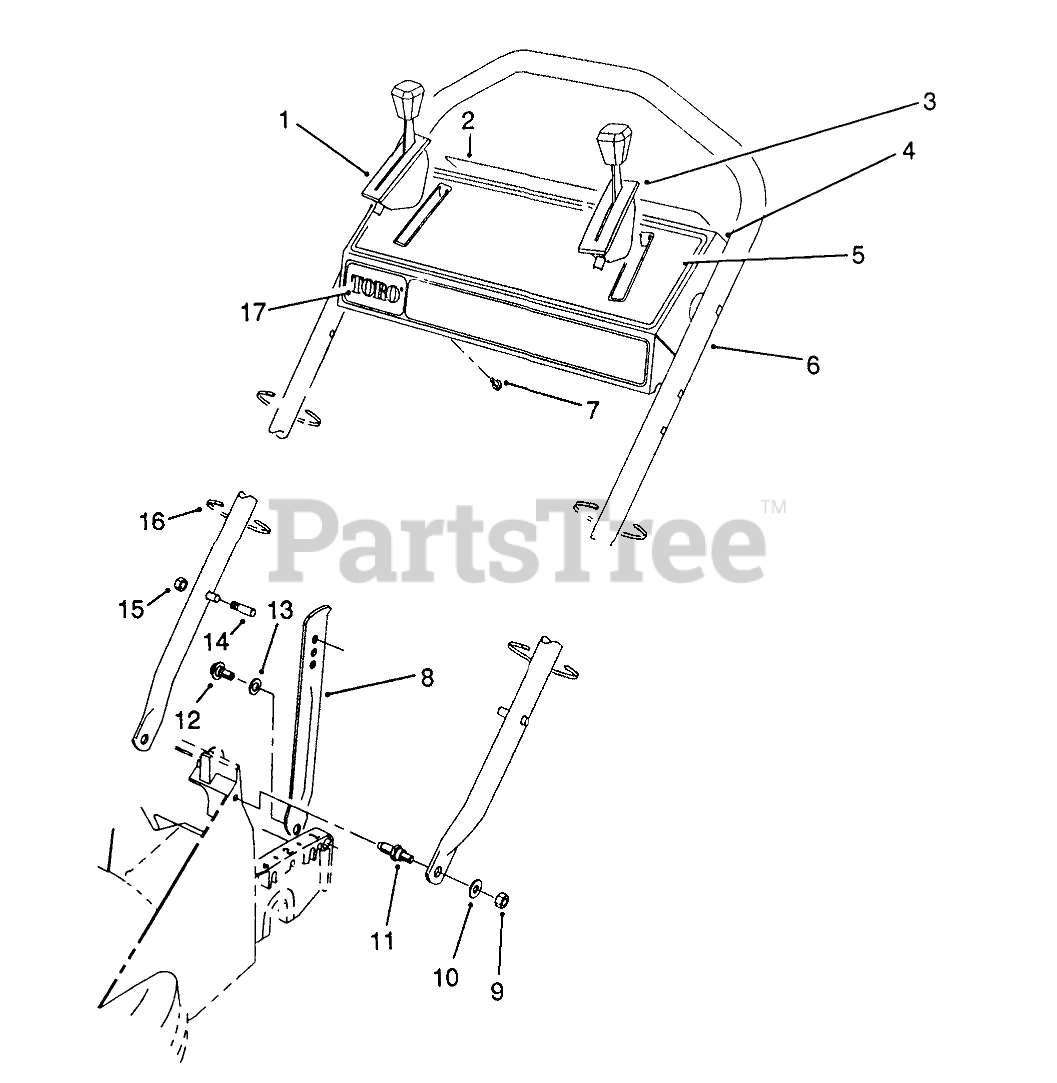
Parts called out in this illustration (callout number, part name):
1	Control-Ground Speed
2	DECAL - PANEL, REAR
3	THROTTLE CONTROL
4	Control Panel Assembly (Incl. Ref. #2, 5)
5	DECAL - INSTRUCTION
6	HANDLE
7	SCREW-HWHTF
8	HANDLE LATCH
9	NUT-LOCK, NI
10	WASHER-PLAIN
11	SCREW - SHOULDER STUD
12	SCREW-SHOULDER
13	NYLON WASHER
14	HANDLE PIN
15	NUT-LOCK, NI
16	TIE-CABLE
17	DECAL - TORO PANEL
